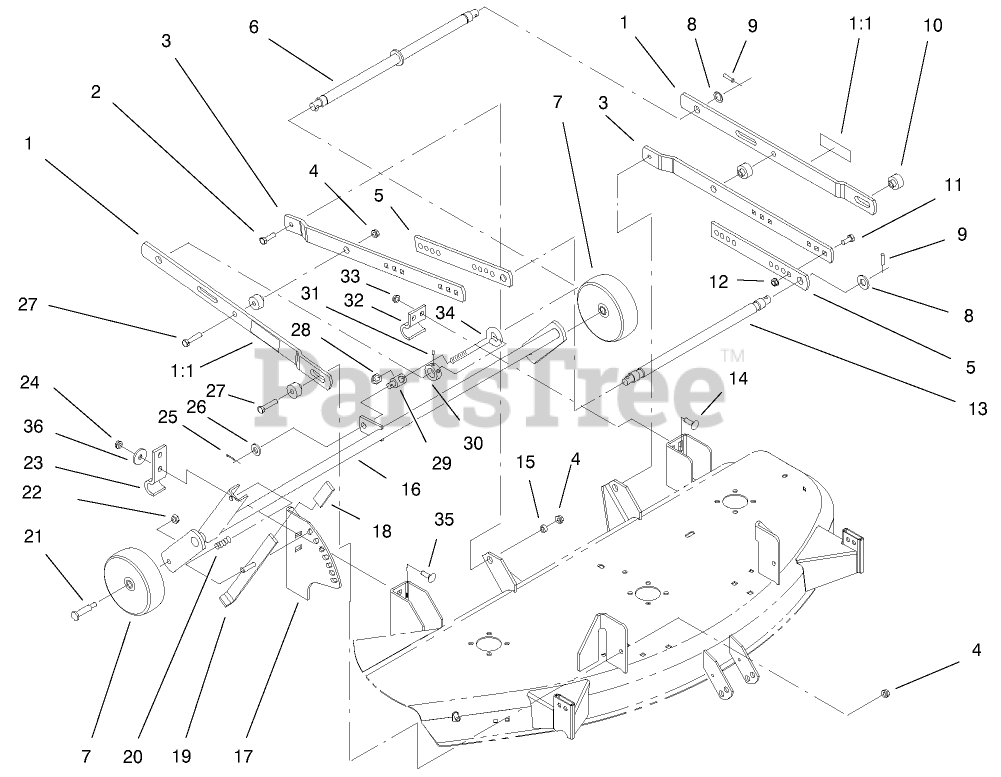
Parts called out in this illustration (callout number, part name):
1	LH LEVELER ASM *B
1	BAR-LEVELER
1:1	DECAL-WARNING
2	SCREW-HH
3	DRAFTBAR
5	DRAFTBAR-ADJUSTMENT
6	SHAFT-LEVELER
7	WHEEL
8	WASHER-FLAT
9	PIN-ROLL, SPIROL
10	SPACER
11	SCREW-CARR
12	NUT-LOCK, CONE
13	SHAFT-DRAFTBAR
14	BOLT-CARR
15	SPACER
16	SUPPORT-WHEEL
17	QUAD-DECK, 42"/48"
19	LEVER ASM-HOC
20	SPRING-COMPRESSION
21	BOLT-SHOULDER
23	BRACKET-PIVOT
24	NUT-LOCK, NI
25	PIN-COTTER
26	WASHER-FLAT
27	SCREW-HH
28	NUT-LOCK, NI
29	TRUNNION
30	COLLAR
31	SCREW-SET, HSH
33	NUT-FLANGE
34	ROD-ADJUSTMENT, LEVEL
35	SCREW-CARR
36	WASHER-SUPPORT
